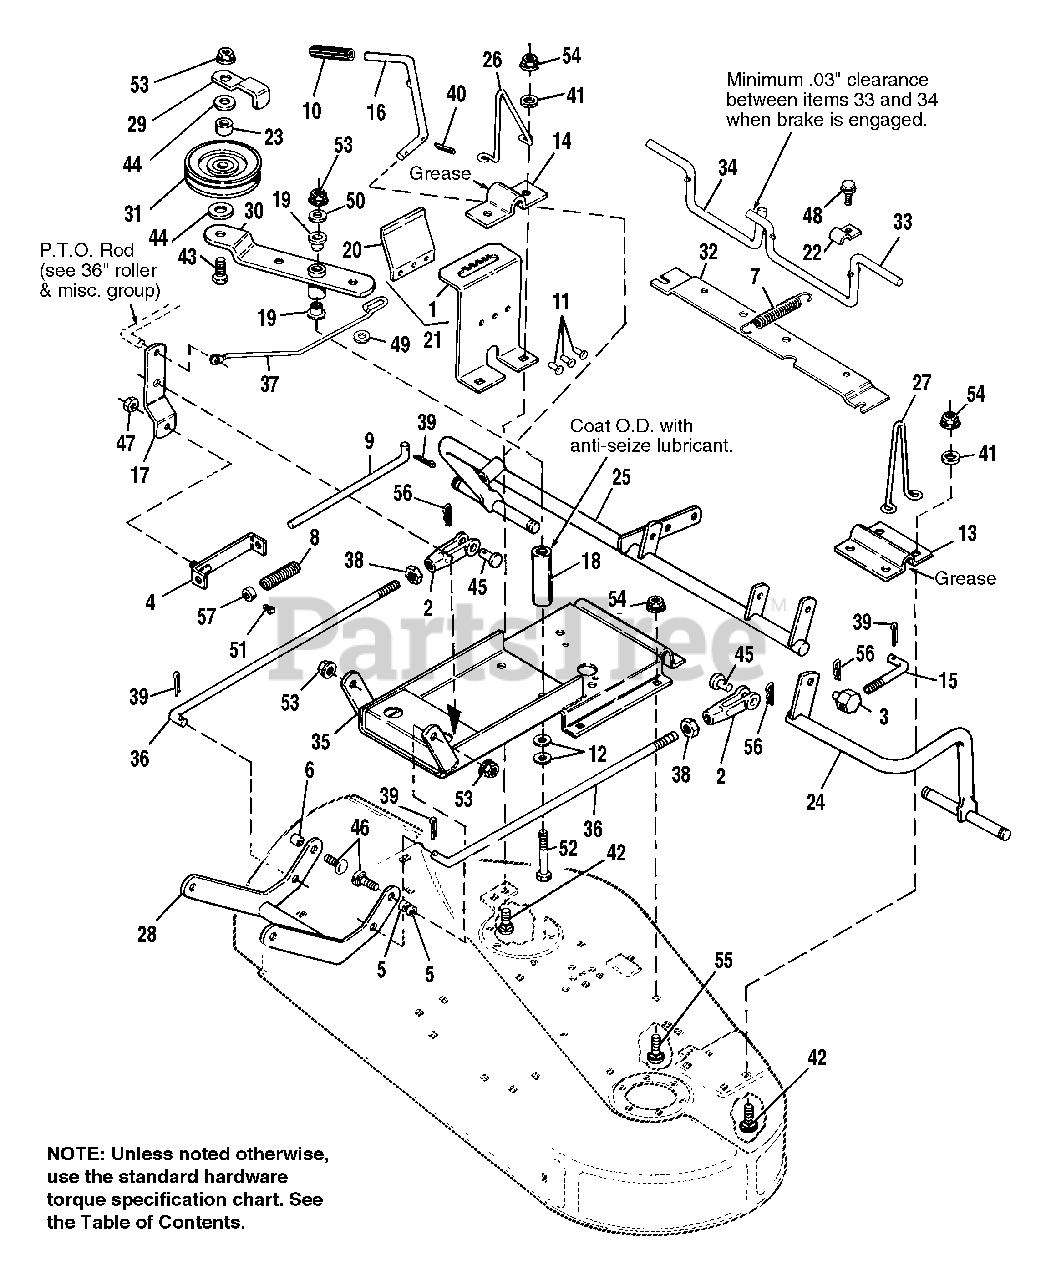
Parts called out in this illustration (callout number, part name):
2	CLEVIS, Adjusting
4	GUIDE ASSY., Rod
9	ROD, Clutch
10	GRIP, Handle
11	RIVET, Tubular, 3/16 x 5/16
13	CLAMP, Adjusting, Wheel Support
16	LEVER, Control
19	BUSHING, Universal
20	SPRING, Flat
21	QUADRANT ASSY.
22	CLIP, Brake Rod
24	SUPPORT ASSY., Roller, LH
25	SUPPORT ASSY., Roller, RH
26	UP-STOP, R.H.
27	UP-STOP, L.H.
28	ARM ASSY., Rocker
29	GUARD, Spring
30	LEVER ASSY., Clutch
31	PULLEY ASSY.
32	SUPPORT, Brake
35	SUPPORT ASSY., Mower
36	ROD, Height Adjustment
38	NUT, Hex, Full, 3/8-16
39	PIN, Cotter, 3/32 x 3/4
40	COTTER PIN
41	WASHER, Plain
42	CARRIAGE BOLT, 5/16-18 x 1-1/4
43	CAPSCREW, Hex Hd., 3/8-16 x 1-3/4
44	WASHER, Plain
45	PIN, Clevis
46	CARRIAGE BOLT, 3/8-16 x 1-1/4
47	LOCKNUT, Hex, 5/16-18
48	SCREW, Hex Hd., Taptite, 5/16-18 x 1/2
49	WASHER, 13/32
50	WASHER, Plain, 13/32
51	SETSCREW, 1/4-20 x 3/8
52	CAPSCREW, Hex Hd., 3/8-16 x 2-3/4
53	NUT, Hex Flange, 3/8-16
54	NUT, Hex, Flange, Whizlock, 5/16-18
55	CARRIAGE BOLT, 5/16-18 x 3/4
56	CLIP, Hair Pin
57	COLLAR, Set
